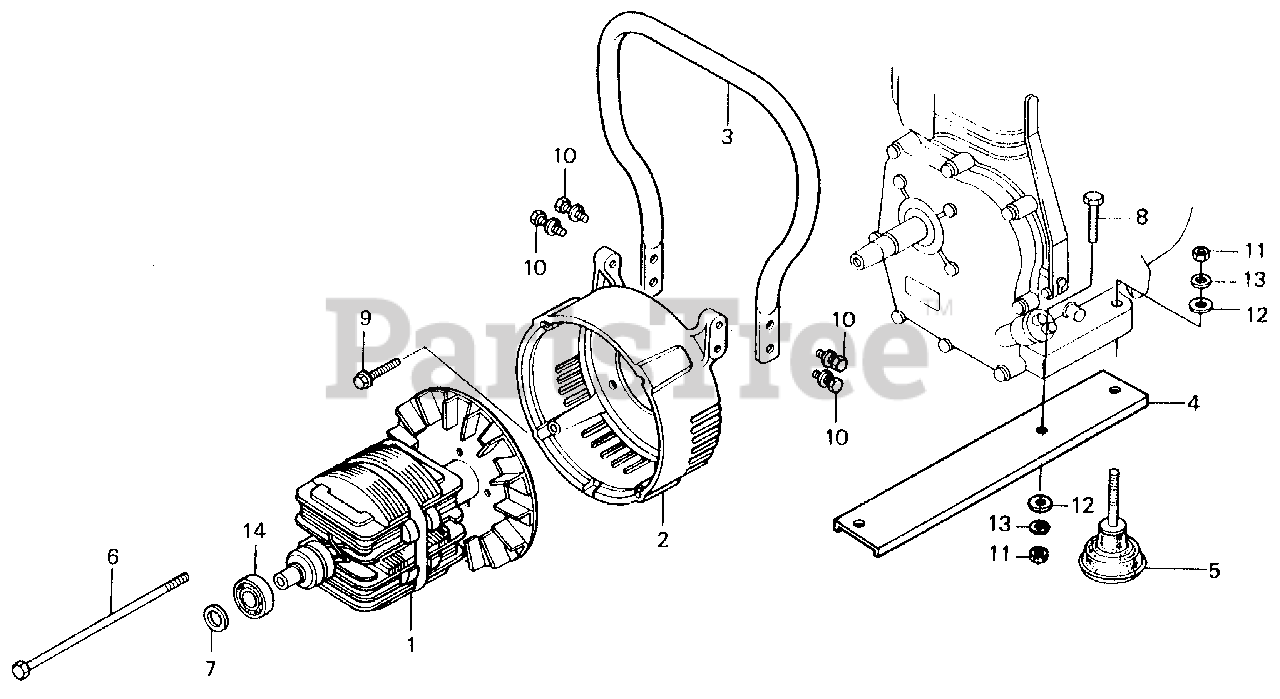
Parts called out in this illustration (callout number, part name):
2	HOUSING, FR. *R8* (BRIGHT RED)
3	HANDLE, CARRY (NOT AVAILABLE)
4	BED, FRAME
5	RUBBER (LOWER)
6	BOLT, HEX. (5/16X160)
7	WASHER (8MM)
8	BOLT, HEX. (8X35)
9	BOLT-WASHER (8X25) (SOURCE: VINTAGE PARTS INC.)
9	BOLT-WASHER (8X35) (NOT AVAILABLE)
10	BOLT-WASHER (8X25) (NOT AVAILABLE)
11	NUT, HEX. (8MM)
11	NUT, FLANGE (8MM)
12	WASHER, PLAIN (8MM)
13	WASHER, SPRING (8MM)
14	BEARING, RADIAL BALL (6203UU)
